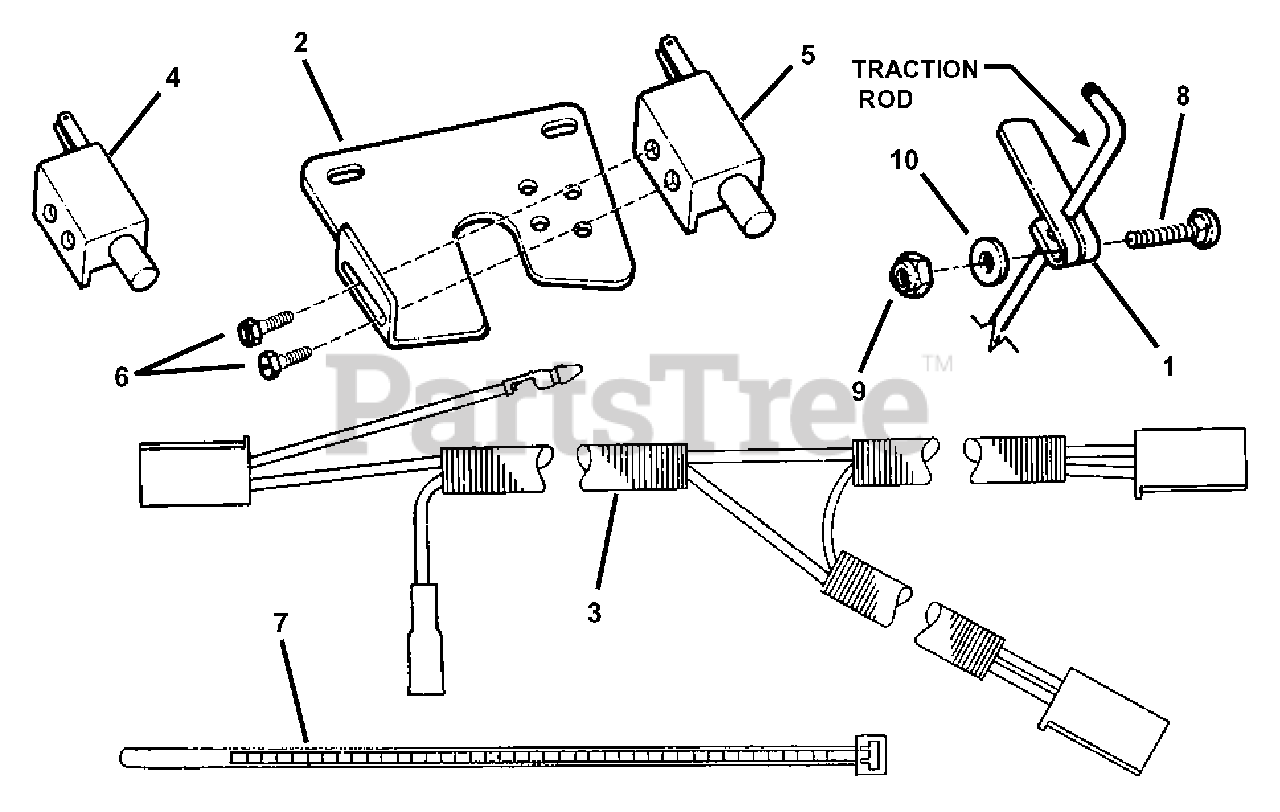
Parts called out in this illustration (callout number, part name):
1	TAB, Traction Switch
2	PLATE, Switch
3	HARNESS
4	SWITCH, SP/NC Gray
5	SWITCH, NO Black
6	SCREW, #12-14 x 1/2" Hex Washer Face, Slotted
7	TIE, Plastic
8	BOLT, 1/4-20 x 1-1/4" Square Neck Carriage
9	NUT, 1/4-20 Hex Nyloc
10	WASHER, 1/4" Flat
